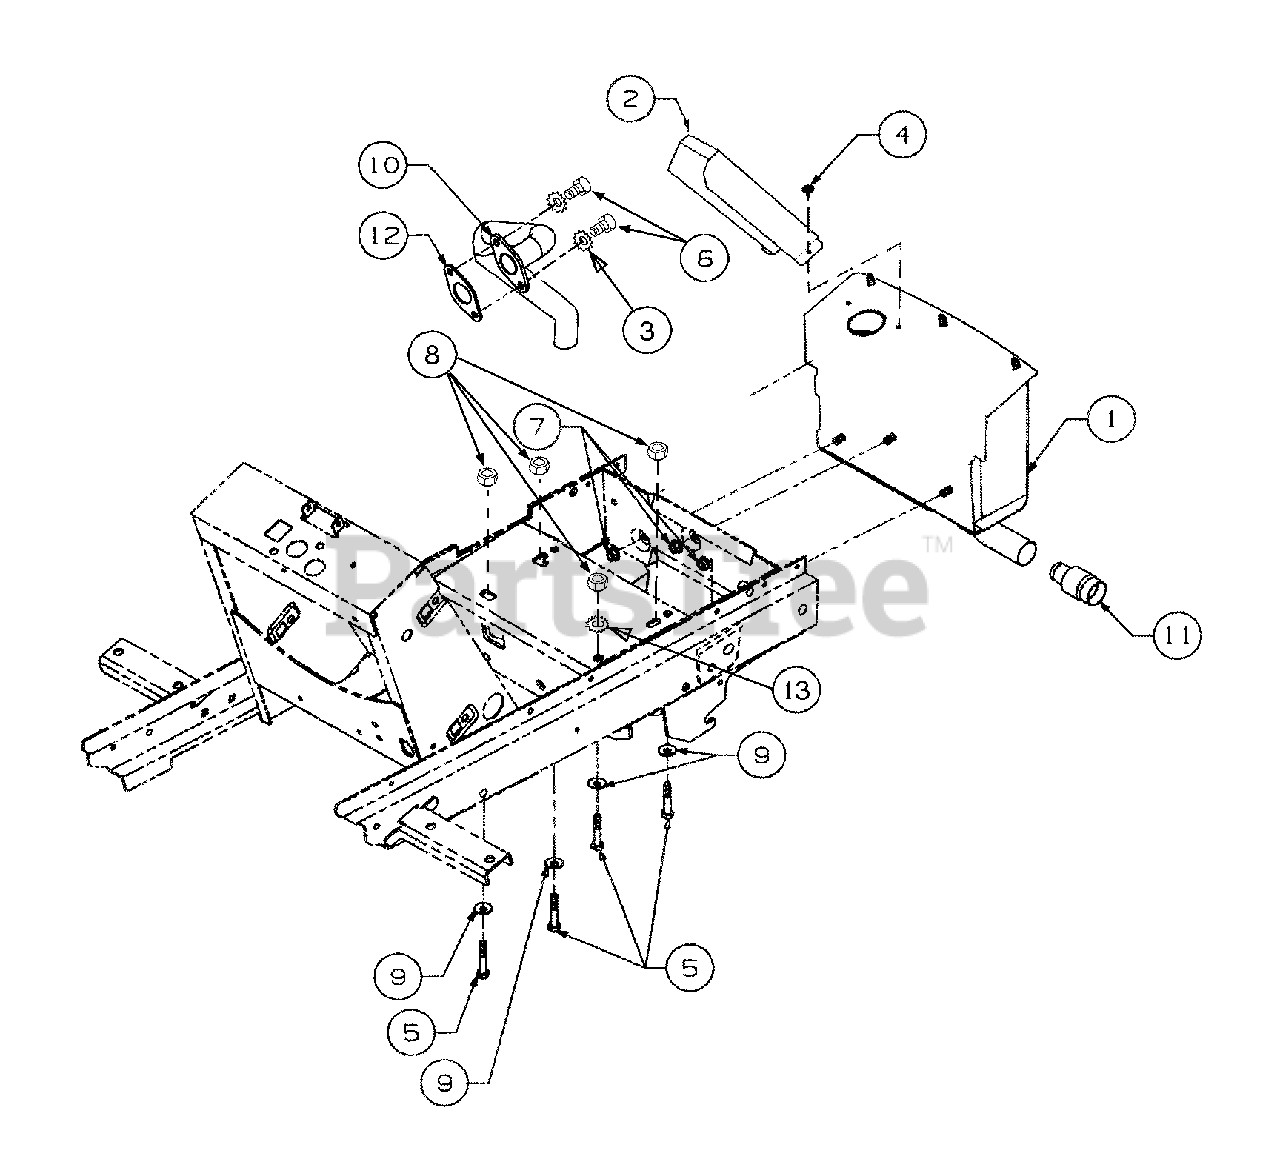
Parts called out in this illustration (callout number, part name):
1	Muffler Assembly
2	Sheild, Muffler Tube
3	Washer, External Lock, 5/16
4	Screw, Hex Wsh Hd Tap, #10-16 x .38
5	Bolt, Eng Mount, 3/8-24 x 1.75 GR5
6	Screw, Hex Hd Cap, M8 x 1.25 x 14
7	Nut, Hex Flange Lock, 5/16-18
8	Nut, Hex Lock, 3/8-24
9	Washer, Bell, .380 x .88 x .062
10	Tube, Exhaust
11	Arrestor, Spark
12	Gasket, Exhaust
13	Washer, External Lock, 3/8
